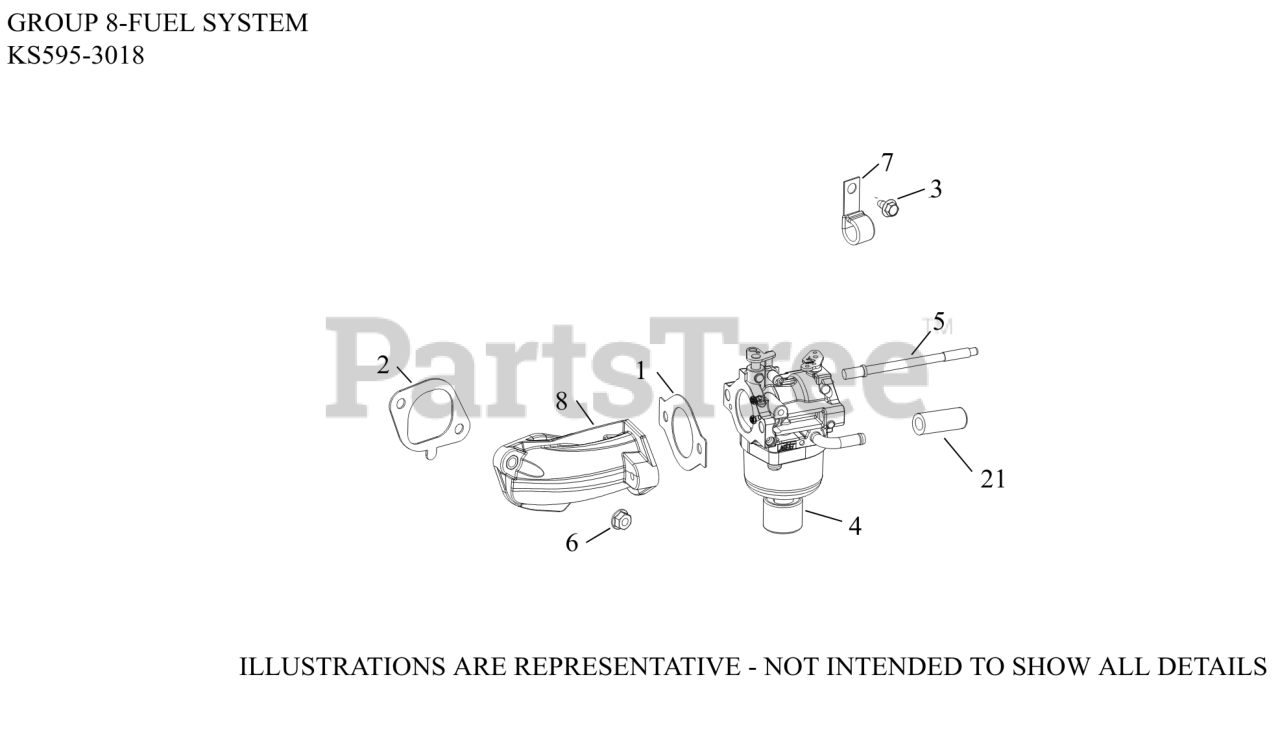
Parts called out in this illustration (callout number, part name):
1	GASKET, CARBURETOR (THROTTLE)
2	GASKET, INTAKE MANIFOLD
3	SCREW, THREAD FORMING
4	KIT,CARB(NIKKI)
5	STUD, CARBURETOR
6	NUT, FLG M6X1.0
7	CLIP, CABLE
8	MANIFOLD, INTAKE ASSEMBLY
NI	HIGH ALTITUDE KIT (5000 FT)
NI	KIT, OVERHAUL
NI	KIT, CHOKE SHAFT
NI	KIT, O-RING
NI	KIT, SOLENOID (NIKKI)
NI	KIT, BOWL WITH O-RINGS
NI	KIT, FLOAT AND INLET NEEDLE FOR GRAVITY
NI	KIT, THROTTLE SHAFT
NI	MASKING CAP
